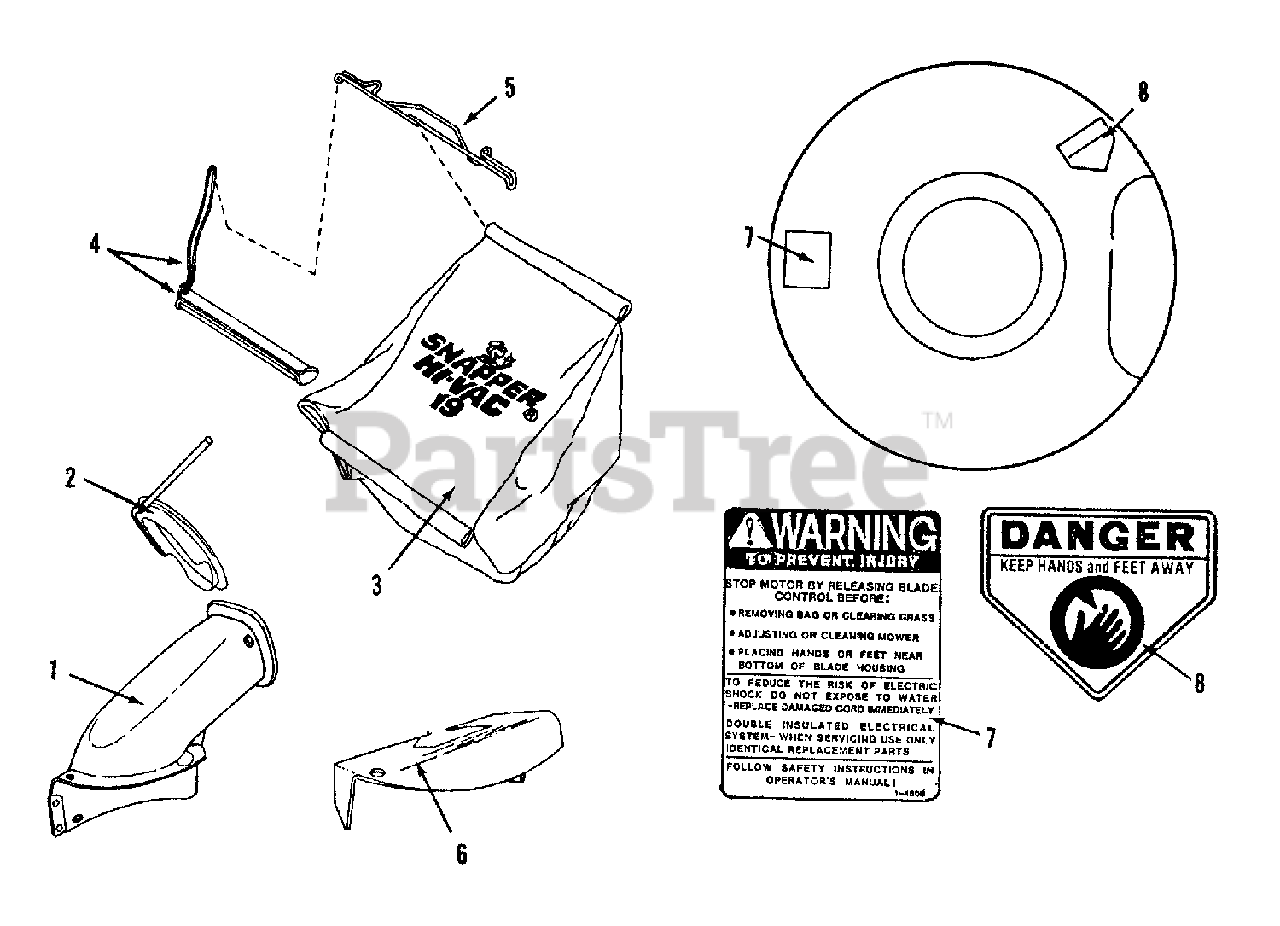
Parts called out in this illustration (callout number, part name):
1	ADAPTER, Bag
2	CONNECTOR, Bag
3	BAG, Grass
4	ASSEMBLY, Rope & Slider
5	WIRE, Rear Bag
6	CHUTE, Side 19"
7	DECAL, Warning
8	DECAL, Danger (Keep Hands & Feet Away)
